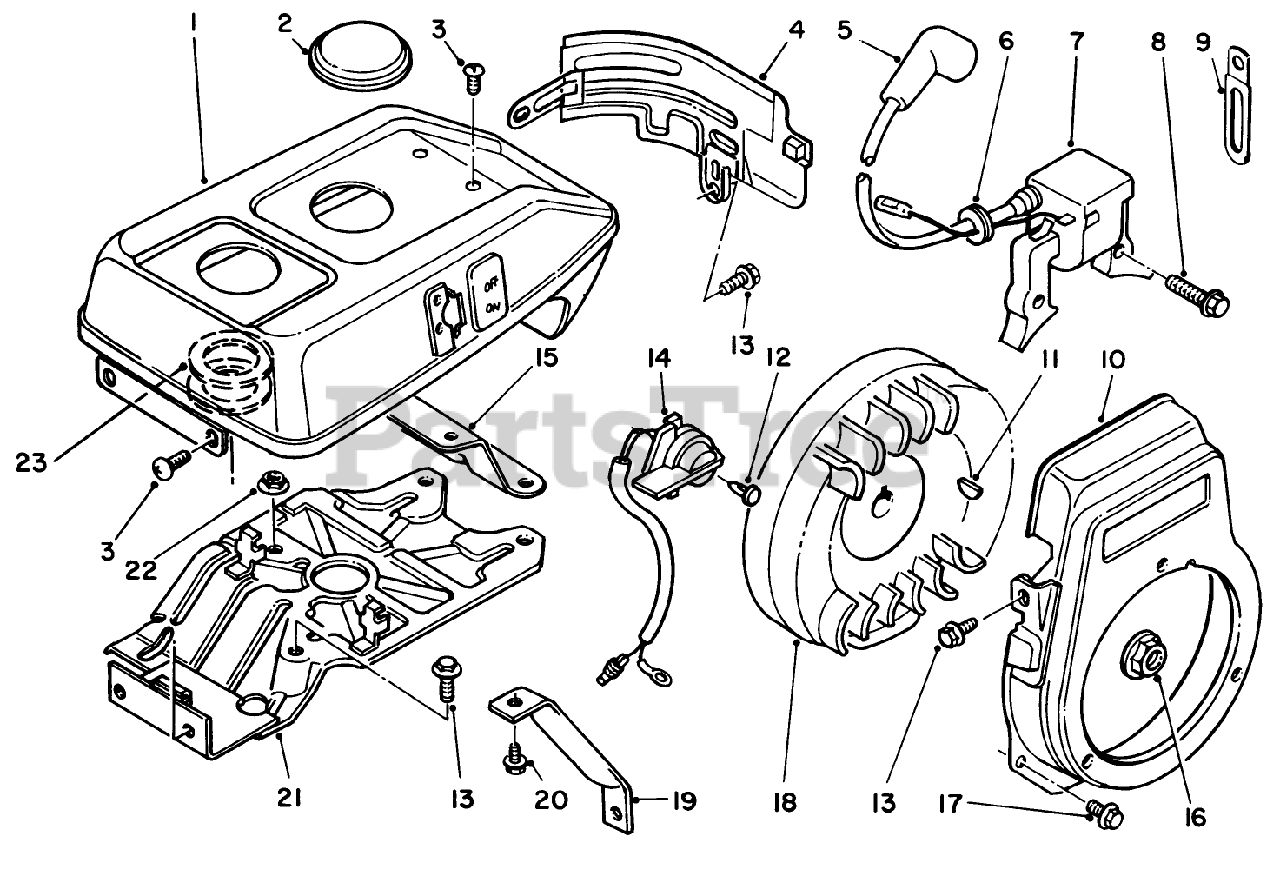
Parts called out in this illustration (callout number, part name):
1	Cover-Engine
3	Screw-Round Phillips Hd.
4	Cowling-Side
5	CAP-SPARKPLUG
6	Grommet
7	Magneto Assembly (Incl. Ref. #5 & 6)
9	CLAMP
10	Cover-Cooling Fan
14	Switch-Engine
15	Bracket-Engine Cover
18	Rotor
19	Support-Fuel Tank
20	SCREW-HHF
21	Cowling-Upper
23	Washer
